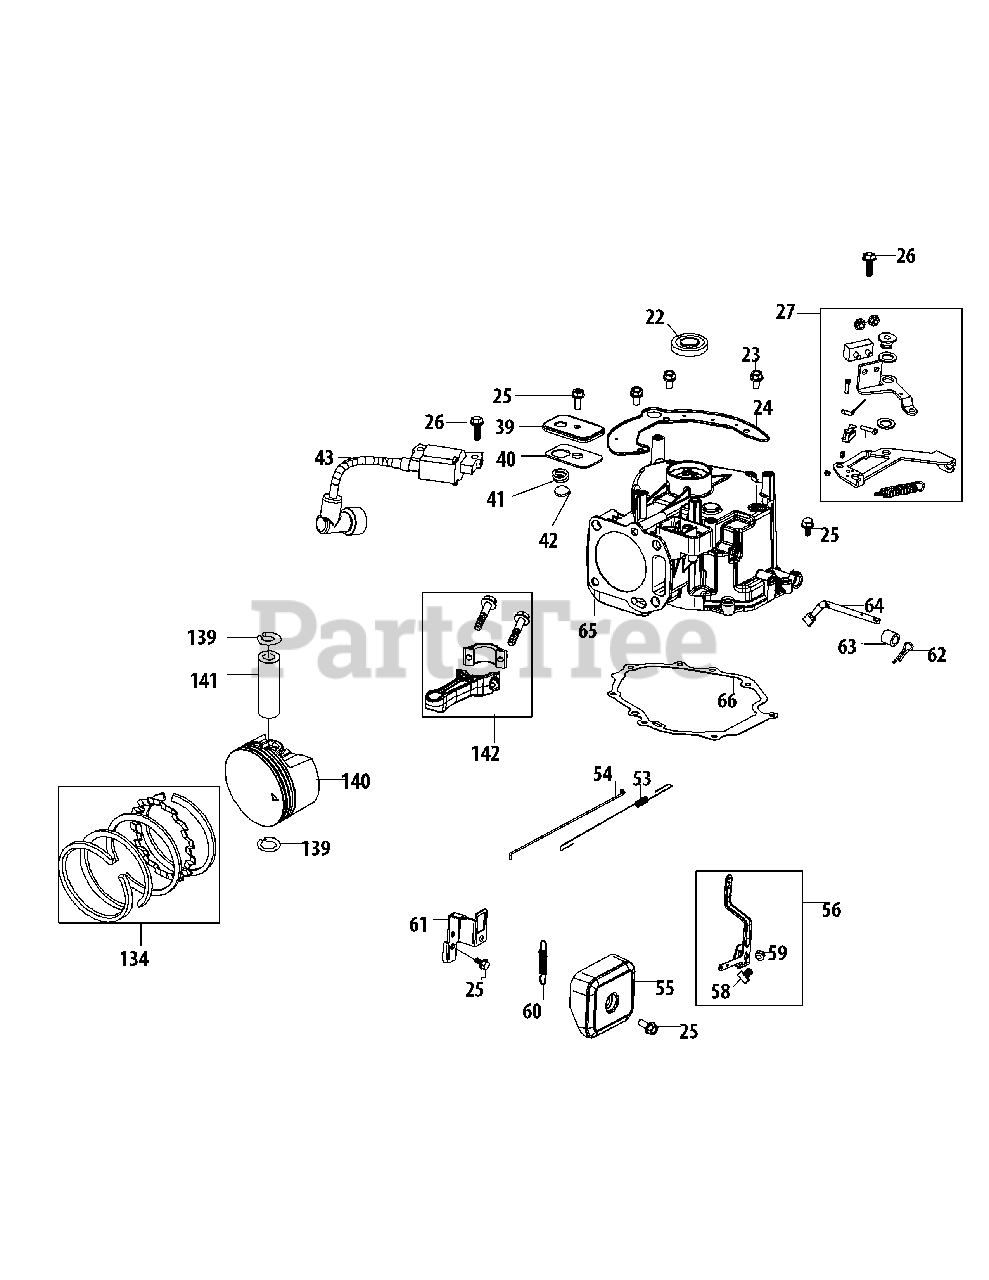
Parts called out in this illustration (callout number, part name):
22	Upper Crankshaft Seal
23	Bolt M6×10 Shroud Cover Plate
24	Shroud Cover Plate
25	Bolt M6X14 Multi-Purpose
26	Bolt M6×25 Ign/Brake/Cvr Plt
27	Brake Assembly
39	Breather Cover Plate
40	Breather Gasket
41	Breather Valve Spring
42	Breather Valve
43	Ignition Coil Assembly
53	Throttle Linkage Spring
54	Throttle Linkage
55	Governor Shield
56	Governor Arm Assembly
58	Governor Arm Bolt
59	Governor Arm Nut M6
60	Governor Spring
61	Component Bracket
62	Governor Arm Shaft Cotter Pin
63	Governor Seal
64	Governor Arm Shaft
65	Crankcase
65	(Mtd Srvc Kit) Short Block
66	Crankcase Cover Gasket
134	Piston Ring Set
139	Piston Pin Snap Ring
140	Piston
141	Piston Pin
142	Connecting Rod Assembly
